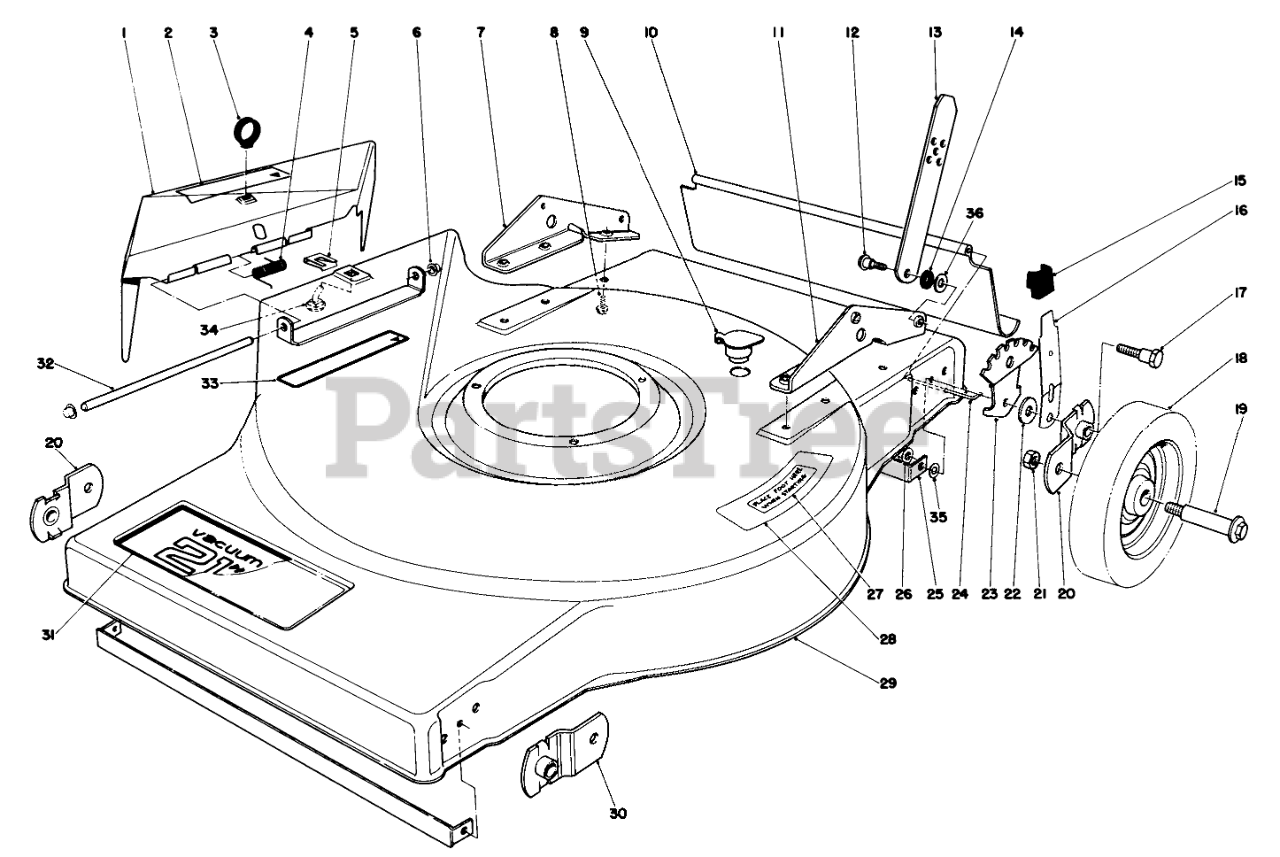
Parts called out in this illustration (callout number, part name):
1	DefIector
2	Caution Decal
3	LIFT LOOP
4	TORSION SPRING
5	BAG CHUTE CLIP PIN
6	PUSHNUT-CAP, WASHER
7	Bracket Handle R.H.
8	SCREW-HWHTF
9	WASHOUT PLUG
10	SAF SHIELD REAR
11	Bracket-L.H.
12	SCREW-SHOULDER
13	Handle Latch
14	SPACER
15	KNOB-ARM
16	SPRING ARM ASM
17	PIVOT SCREW
18	Wheel Assembly
20	PIVOT ARM ASM A
21	Nut
22	PIVOT WASHER
23	Quadrant
24	SHIELD ROD
25	DECK SUPPORT
27	Decal Step Pad
28	PAD STEP
29	Housing
30	PIVOT ARM ASM B
31	Decal Deck
32	DEFLECTOR PIVOT ROD
33	Decal Warning
34	BAG CHUTE PIN
35	WASHER
36	WASHER-PLAIN
